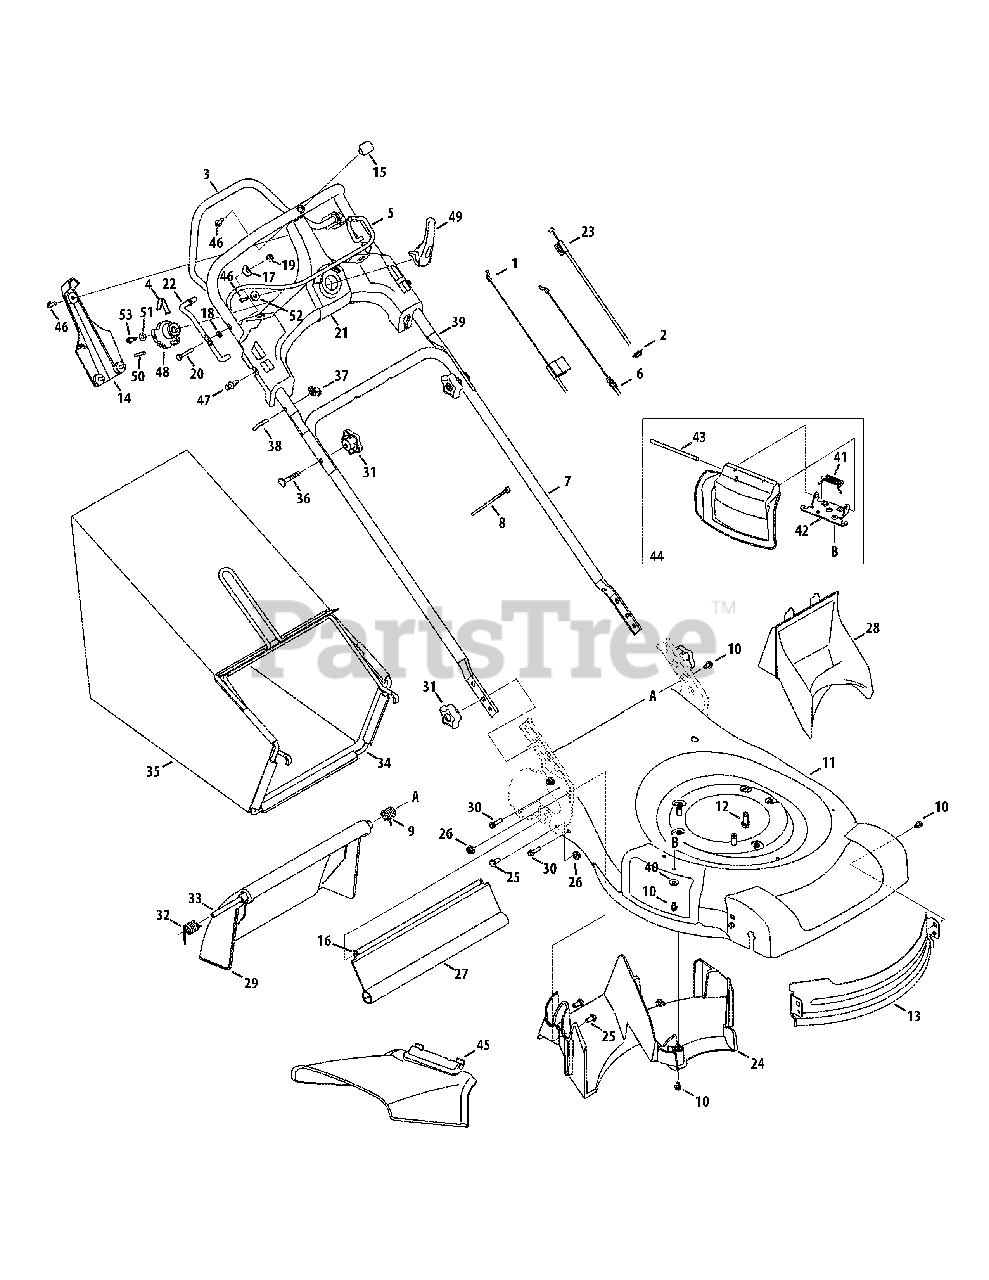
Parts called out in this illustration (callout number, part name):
1	Drive Cable
2	Rubber Grommet
3	Drive Control
4	Shift Spring
5	Blade Control
6	Control Cable
8	Cable Tie
9	Torsion Spring, LH
10	TT Screw, 1/4-20 x .500
13	Front Deck Baffle
14	Variable Speed Cont. Panel Cover
15	Variable Speed Cont. Panel Cover
16	Screw, #10-16 x .500
17	Saddle Washer
18	Washer, Lock, 1/4
19	Nut, Flange Lock, 1/4-20
20	Screw, 1/4-20 x 1.50
21	Variable Speed Control Panel
22	Bail Pivot Rod - RH
22	Bail Pivot Rod - LH
23	Variable Speed Cable
24	Rear Baffle
25	Screw, 5/16-18 x .625
26	Flange Lock Nut, 5/16-18
27	Trailshield
28	Mulch Plug
29	Rear Door
30	Screw, 1/4-15 x 1.00
31	Star Knob
32	Torsion Spring, RH
33	Door Pivot Rod
36	Carriage Bolt, 5/16-18 x 2.00
37	Wing Nut
38	Eye Bolt
40	Bell Washer, .265 x .75 x .062
41	Torsion Spring
42	Chute Deector Adapter
43	Hinge Pin
44	Mulch Plug Assembly
45	Side Discharge Chute
46	Screw, #12-16 x .75
47	Rivet, Plastic
48	4 Speed Actuator
49	Speed Selector Level
50	Dowel Pin
51	Washer, Flat, .344 x .688 x .065
52	Washer, Flat, .250 x .750 x .119
53	Screw, 1/4-15 x .750
